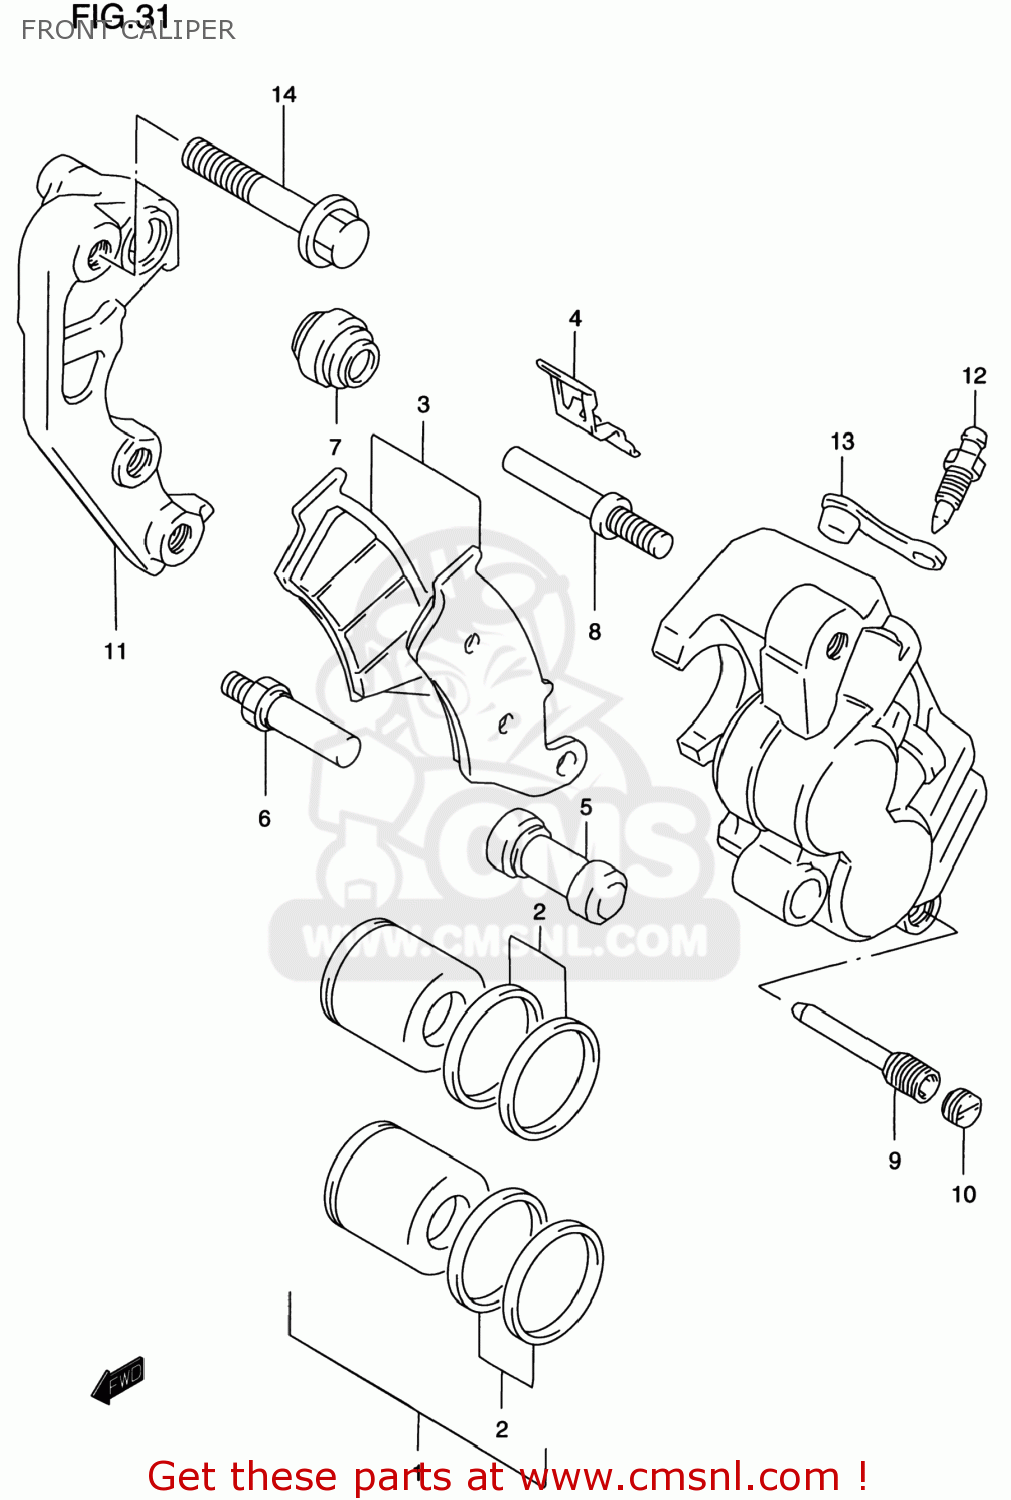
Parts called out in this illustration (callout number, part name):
1	PISTON SET
2	SEAL SET,PISTON
3	PAD SET (NAS)
4	SPRING,PAD
5	BOOT
6	BOLT
7	BOOT
8	PIN
9	PIN,HANGER
10	PLUG,PIN
11	BRACKET
12	BLEEDER
13	CAP,BLEEDER
14	BOLT(8X40)
